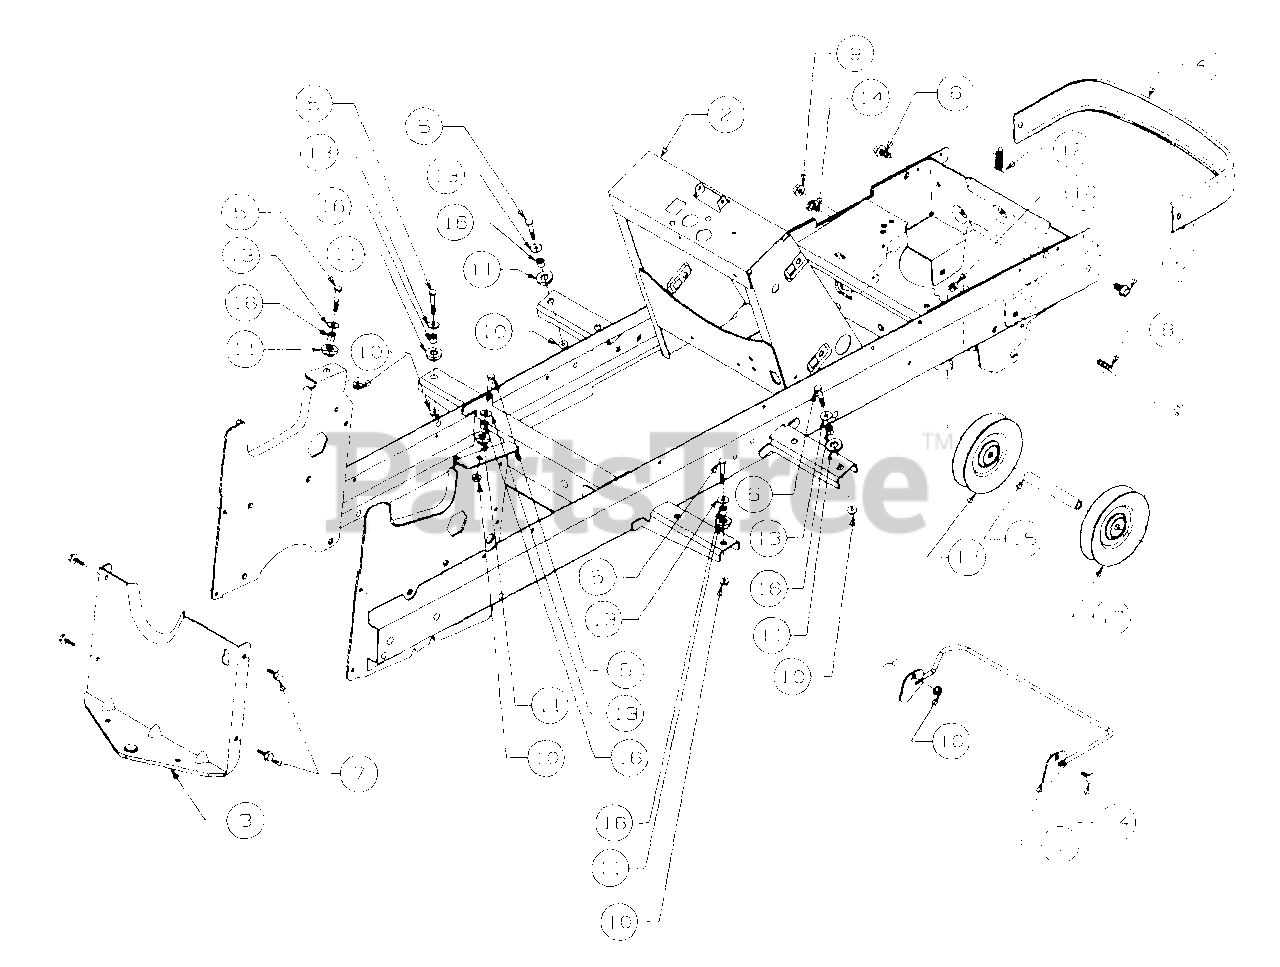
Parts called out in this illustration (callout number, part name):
1	Rod, Quick Attach
2	Frame
3	Drawbar
4	Bumper
5	Screw, Hex Cap, 1/4-20 x 1.0
6	Screw, Hex Wash Hd Tap, 3/8-16 x .75
7	Screw, Hex Wsh Hd Tap, 5/16-18 x.75
8	Screw, Hex Cap, 3/8-16 x 7.0
9	Nut, Hex Flanged Lock, 3/8-16
10	Nut, Hex Flange Lock, 1/4-20
11	Grommet, Insolator
12	Spring, Latch
13	Washer, Flat, .255 x .72 x .60
14	Bolt, Shoulder
15	Spacer, Idler, .407 x .62 x 4.38
16	Spacer, .28 x .40 x .42 Lg
17	Pulley,Idler
